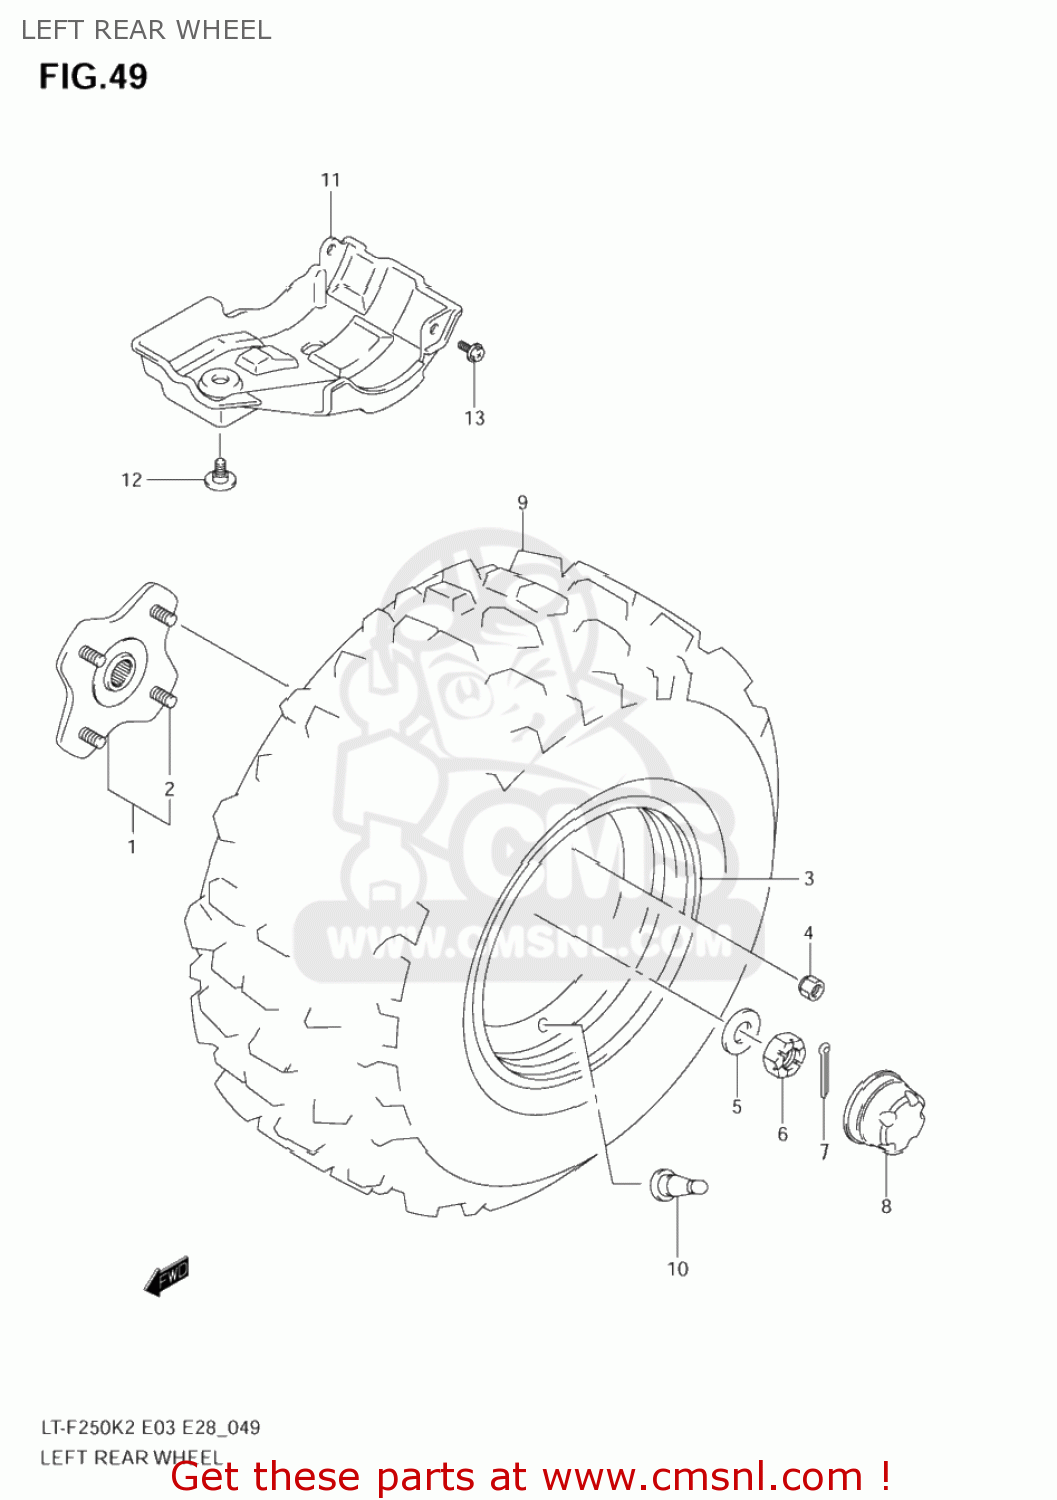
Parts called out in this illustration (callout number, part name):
1	HUB,RR WHEEL,L
2	BOLT
3	RIM,RR WHEEL(9X8.0AT)
4	NUT
5	WASHER
6	NUT
7	PIN, COTTER
8	CAP,WHEEL CTR
9	TIRE,RR
10	VALVE ASSY,WHEEL RIM(TR412)
11	PROTECTOR,FINAL CASE
12	BOLT,PROTECTOR
13	BOLT 6X16.5
